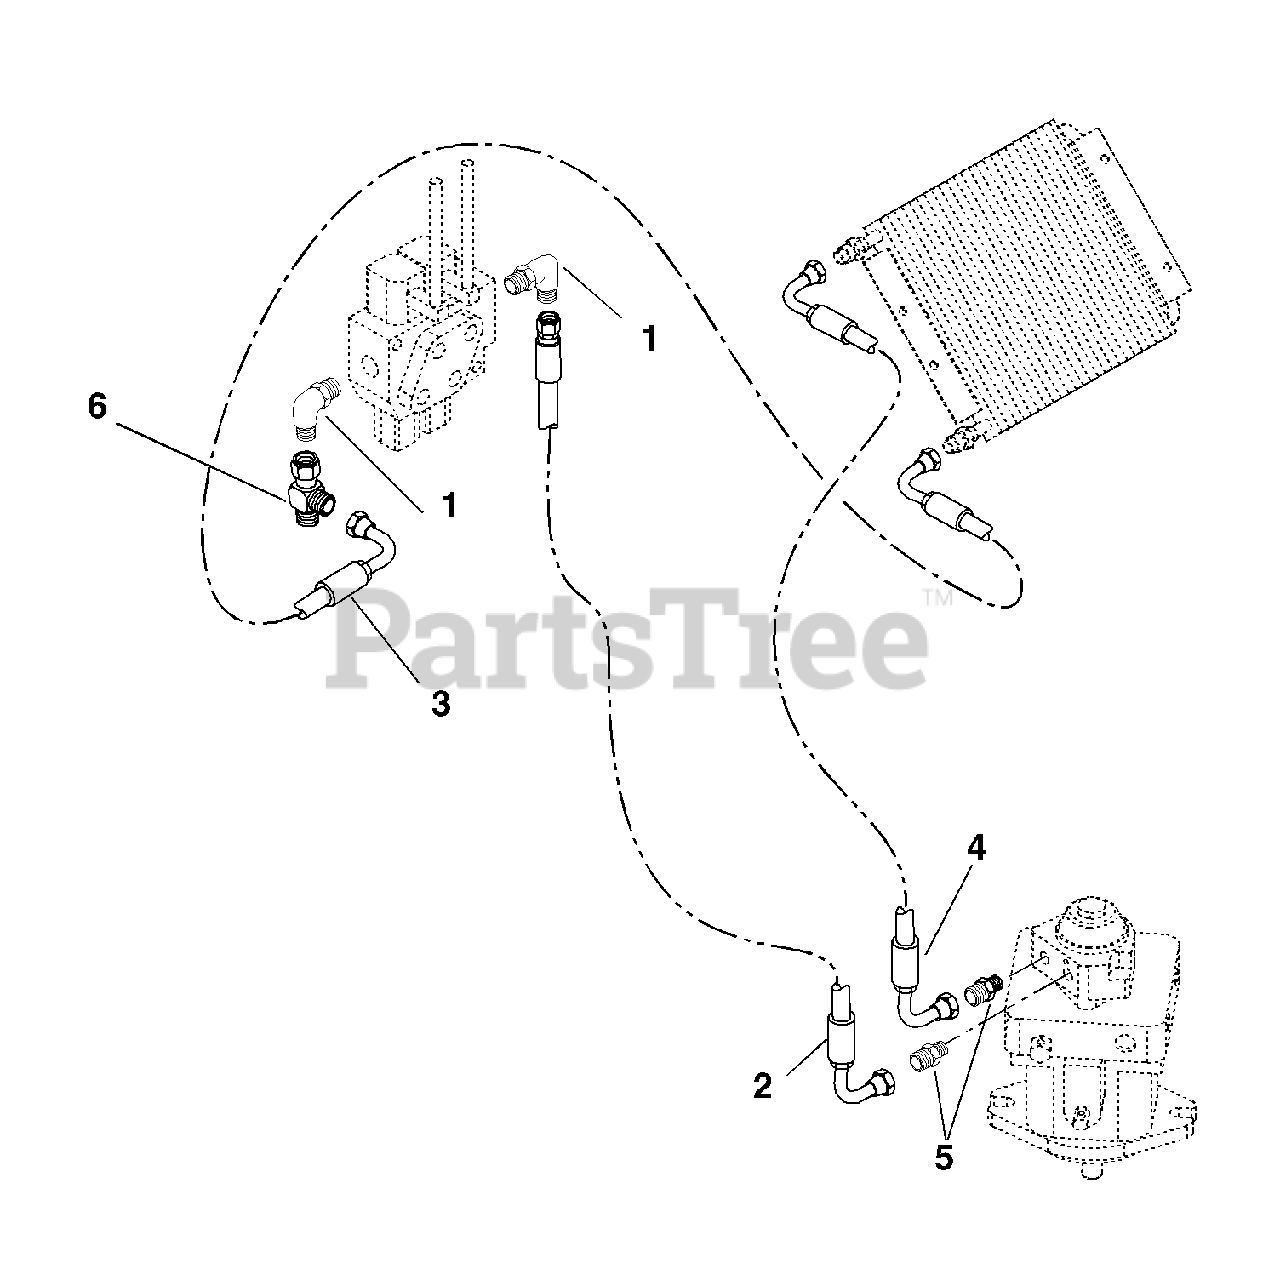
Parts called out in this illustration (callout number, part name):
1	Fitting, Hydraulic Elbow
2	Hose, Hydraulic
3	Hose, Hydraulic
4	Hose, Hydraulic
5	Fitting, Hydraulic
6	Fitting, Hydraulic
